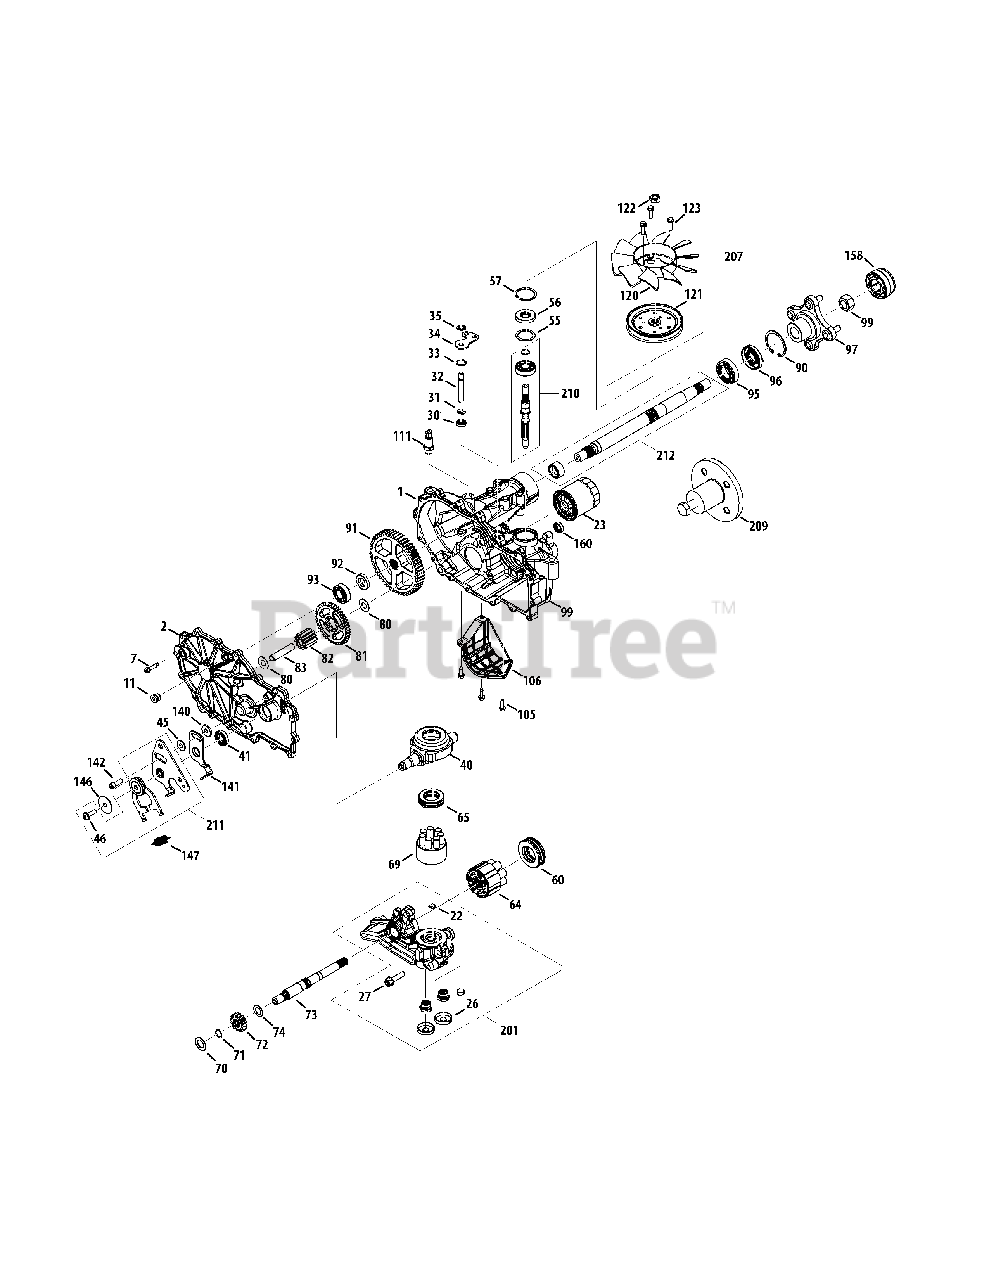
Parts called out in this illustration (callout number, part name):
1	Kit, Housing, Main, LH
2	Kit, Cover, Side, LH
7	Hex Cap Screw, 1/4-20 x 1.125
22	Plate, Bypass
23	Oil Filter
26	Seal, Plug, 1.25 x .25
27	Hex Cap Screw, 3/8-16 x 1.5
30	Seal, Lip .375 x .75 x .25
31	Ring, Ret .375 External
32	Rod, Bypass
33	Ring, Ret .75 Internal
34	Arm, Bypass
35	Ring, Retaining .375 External
40	Trunnion, Swashplate
41	Seal, Lip 12 x 32 x 7
45	Washer, .34 x .88 x .06
46	Hex Cap Screw, 5/16-24 x 1.00
55	Washer, 1.23 x 1.56 x .04
56	Seal, Lip 17 x 40 x 7
57	Ring, Retaining
60	Bearing, Thrust
64	Cylinder Block Assembly
65	Thrust Ball Bearing, 30 x 52 x 13
69	Block 7 Piston Assembly
70	Washer, .63 x 1.0 x .05
71	Retaining Ring, .625
72	Gear, 16t
73	Motor Shaft
74	Washer, .72 x 1.16 x .04
80	Washer, .5 x 1.0 x .03
81	Gear, 43t
82	Gear, 11t
83	Jack Shaft
90	Retaining Ring, 2.06 Internal
91	Gear, 54t
92	Spacer, .75 x 1.32 x .257
93	Ball Bearing, .75 x 40 x 12
95	Ball Bearing, 1.0 x 52 x 15
96	Seal, Lip 25 x 52 x 10
97	Kit, Hub, 4 Bolt
99	Nut, 3/4-16, Hex Lock
105	Hex Cap Screw, 1/4-20 x .75
106	Guard, Filter, LH
111	Fitting, 9/16-18 SAE .5 Barb
120	Fan 7", 10 Blade
121	Disc, Pulley
122	Nut, 1/2-20, Hex Jam
123	Hex Cap Screw, 1/4-20 x .875
140	Spacer, .320 x 1.005 x .179
141	Neutral Right Arm
142	Hex Cap Screw, 5/16-24
146	Washer, .343 x 1.5 x .062
147	Extension Spring, .57 x 2"
160	Seal, Lip, .625 x .875 x .25
201	Kit, Center Section, LH
207	Kit, Fan & Pulley
209	Hub Puller, 4 Bolt
210	Kit, Input Shaft
211	Kit, RTN, Bidirectional
212	Kit, Shaft, Axle
